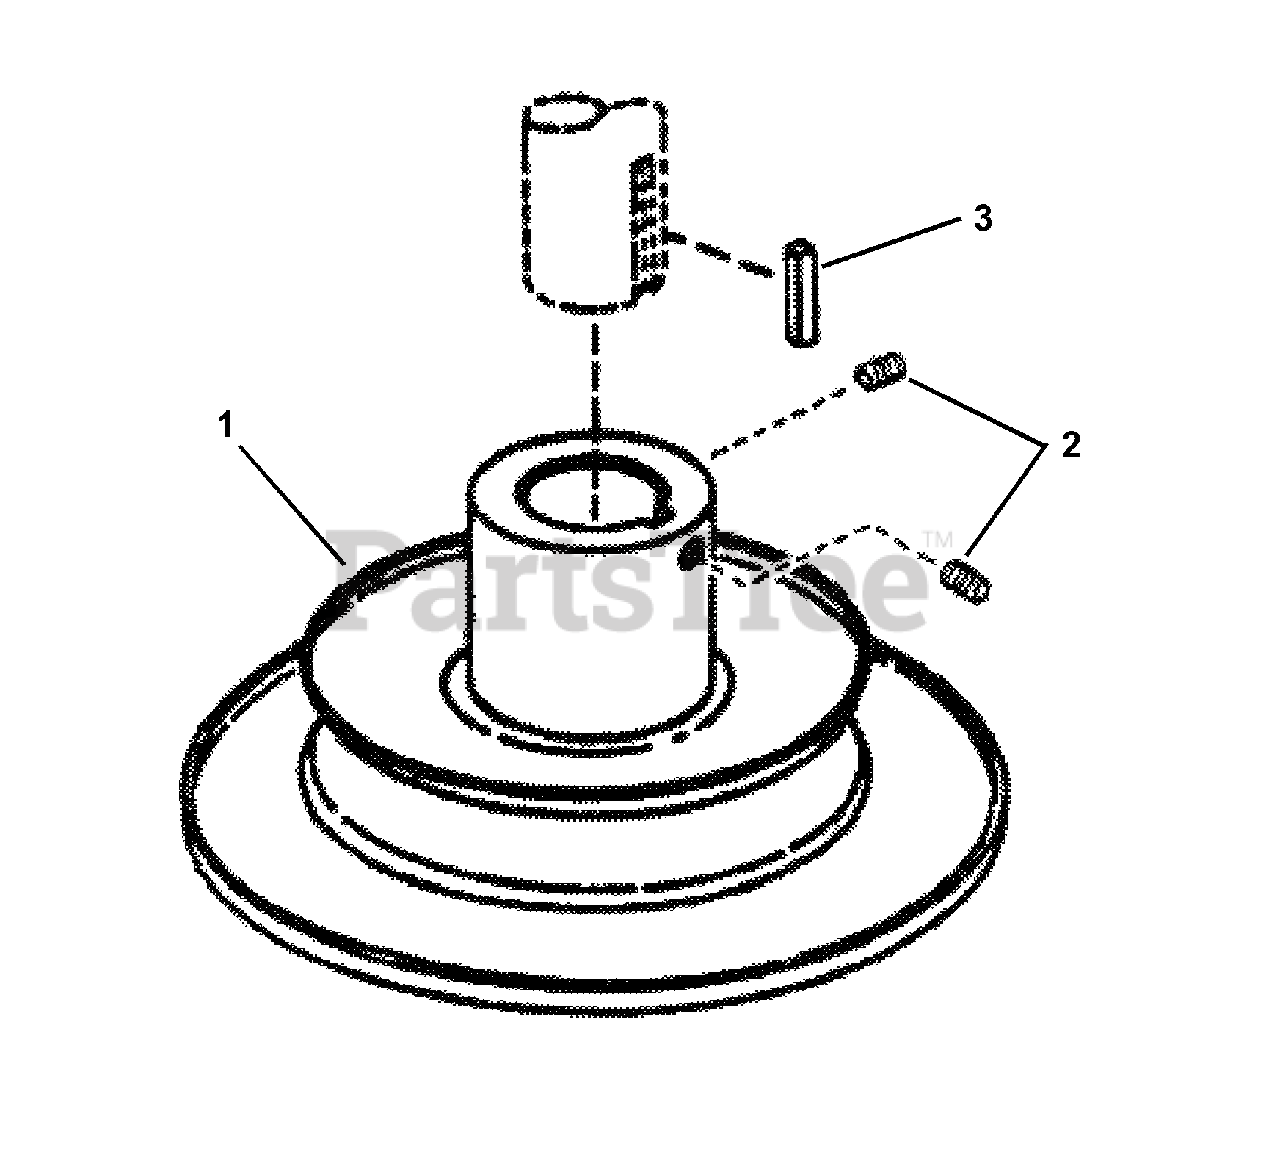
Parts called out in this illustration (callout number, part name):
1	WELDMENT, 5.25" O.D. Drive Disc
2	SCREW, 3/8-16 x 3/8" Set
3	KEY, 1/4" Square x 2"
